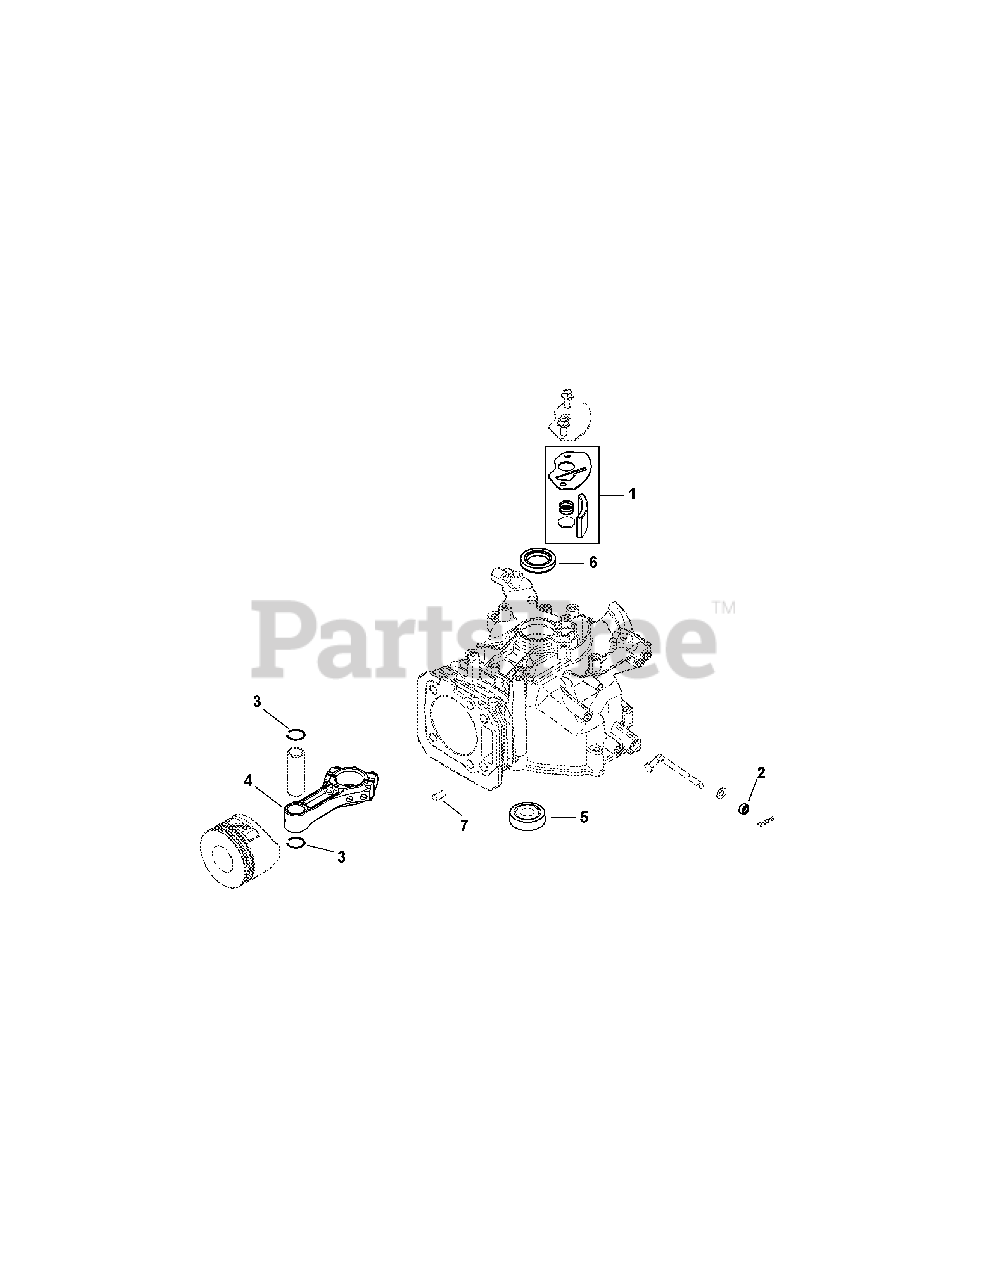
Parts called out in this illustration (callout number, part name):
1	Kit, Breather Filter
3	Retainer, Piston Pin
4	Connecting Rod
5	Bearing, Ball
7	Dowel, Cylinder Head
